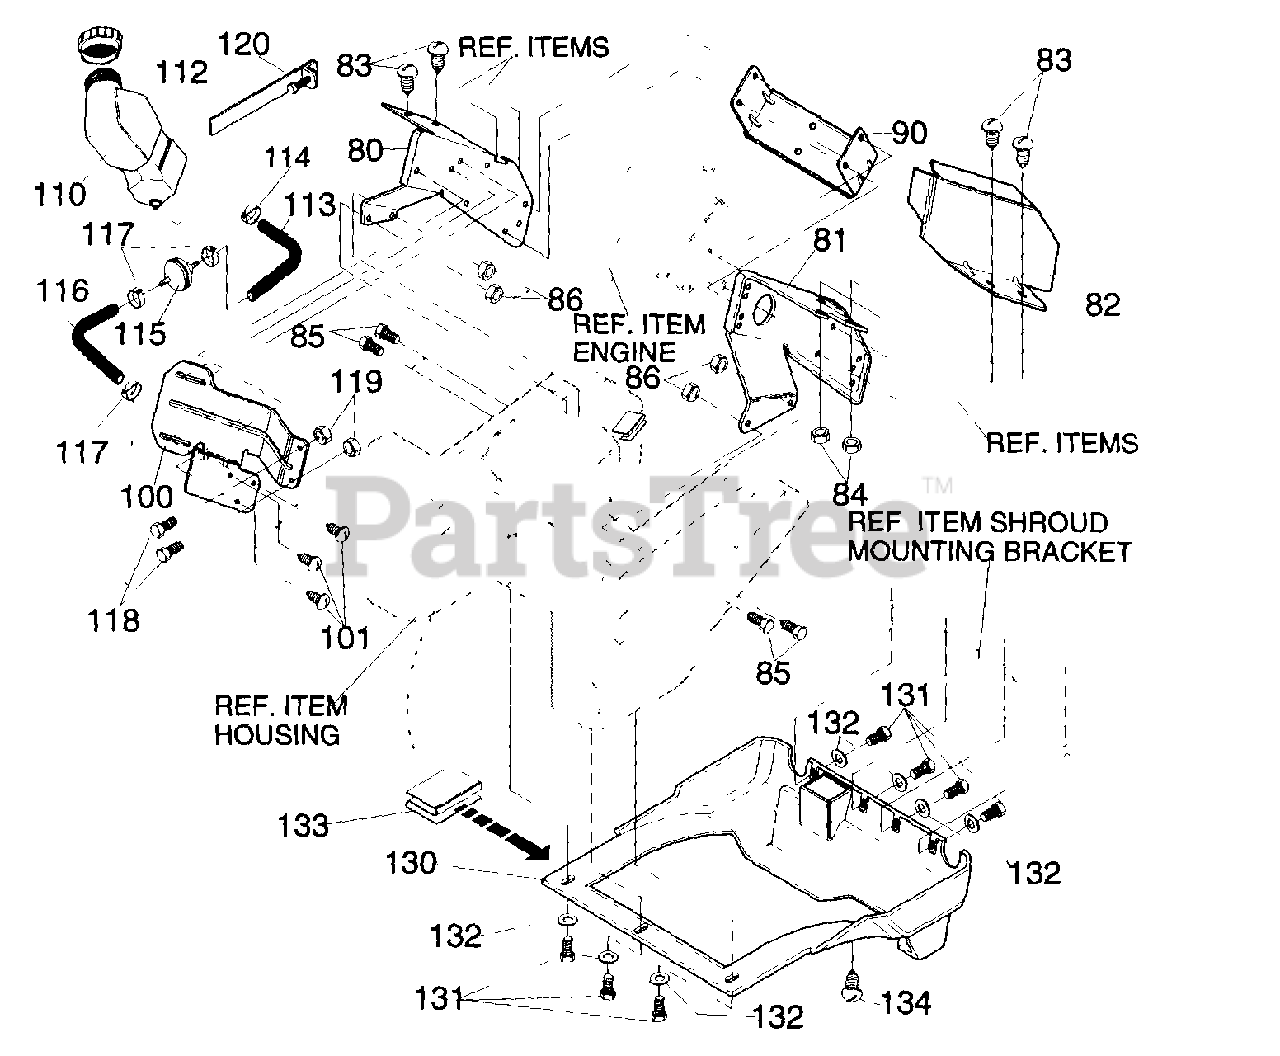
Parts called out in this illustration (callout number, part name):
80	PLATE, REAR MT. RH
81	PLATE, REAR MT. LH
82	SHIELD, ENGINE HEAT
83	SCREW 1/4-20X.63
84	NUT, 1/4-20 MACK LOCK
85	SCREW 5/16-18X.50
86	NUT, 5/16-18 RGHXCTRLK
90	SUPPORT, FRAME ENG MT
100	BRACKET, GAS TANK
101	SCREW, #10-24X.63
110	TANK, FUEL
113	TUBING 8 INCHES
114	CLAMP, HOSE SCREW TYP
115	FILTER, IN LINE
116	TUBING, 3 INCHES
117	CLAMP, HOSE
118	SCREW 10-24X.50
119	NUT, #10-24 REGHXCTRLK
120	CLAMP, WORM
130	SHROUD, BOTTOM
131	SCREW #10-24X.63 TAP
132	FLATWASHER
133	CLIP, "S" TINNERMAN
134	SCREW, 10-16X.50
